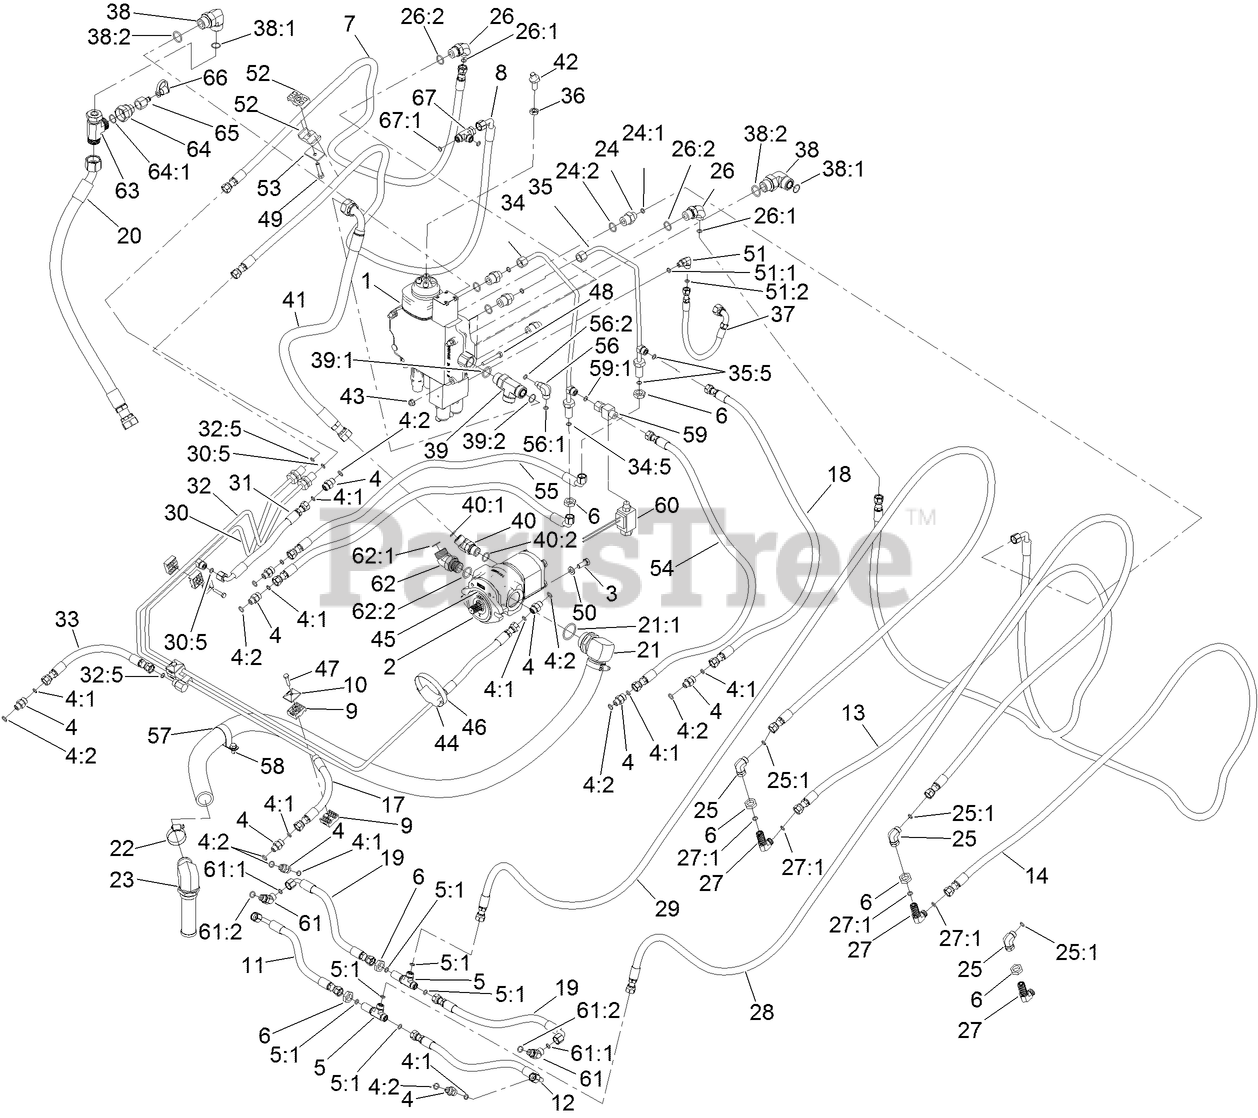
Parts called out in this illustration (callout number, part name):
1	LIFT VALVE ASM
2	GEAR PUMP ASM
3	SCREW-HH
4	FITTING-STRAIGHT
4:1	O-RING
4:2	O-RING
5	FITTING-TEE, BULKHEAD
5:1	O-RING
6	NUT-LOCK
7	HYD HOSE ASM
8	HYD HOSE ASM
9	CLAMP-HOSE
10	PLATE-CLAMP, RETAINER
11	HYD HOSE ASM
12	HYD HOSE ASM
13	HYD HOSE ASM
14	HYD HOSE ASM
18	HYD HOSE ASM
19	HYD HOSE ASM
20	HYD HOSE ASM
21	FITTING-HYD 90 SPCL
21:1	O-RING
23	STRAINER-SUCTION
24	FITTING-STR
24:1	O-RING
24:2	O-RING
25	FITTING-HYD, 90 DEG
25:1	O-RING
26	FITTING-ELBOW 90
26:1	O-RING
26:2	O-RING
27	UNION-BULKHEAD
27:1	O-RING
28	HYD HOSE ASM
29	HYD HOSE ASM
30	HYD TUBE ASM
30:5	O-RING
31	HYD HOSE ASM
32	HYD TUBE ASM
32:5	O-RING
33	HYD HOSE ASM
34	HYD TUBE ASM
34:5	O-RING
35	HYD TUBE ASM
35:5	O-RING
37	HYD HOSE ASM
38	FITTING-ELBOW-90
38:1	O-RING
38:2	O-RING
39	FITTING-TEE
39:1	O-RING
39:2	O-RING
40	FITTING-HYD, 45 DEG
40:1	O-RING
40:2	O-RING
41	HYD HOSE ASM
42	SHAFT-CONTROL
43	NUT-HF, NI
44	BLOCK-HARDLINE
45	O-RING
46	CLAMP-BAND/SCREW
47	SCREW-HH
48	SCREW-HH
49	SCREW-HH
50	WASHER-FLAT
51	FITTING-ELBOW, 90 DEG
51:1	O-RING
51:2	O-RING
52	CLAMP-TUBE
53	COVERPLATE
54	HYD HOSE ASM
55	HYD HOSE ASM
56	FITTING-ELBOW, 90 DEG
56:1	O-RING
56:2	O-RING
57	CLAMP-R
58	SCREW-HWH
59	FITTING-HYD, SPECIAL
59:1	O-RING
60	SWITCH-PRESSURE,
61	FITTING-ELBOW, 45 DEG
61:1	O-RING
61:2	O-RING
62	FITTING-45 DEG
62:1	O-RING
62:2	O-RING
63	FITTING-HYD
64	FITTING-STRAIGHT
64:1	O-RING
65	FITTING
66	CAP-DUST
67	FITTING-TEE, SWIVEL NUT
67:1	O-RING
